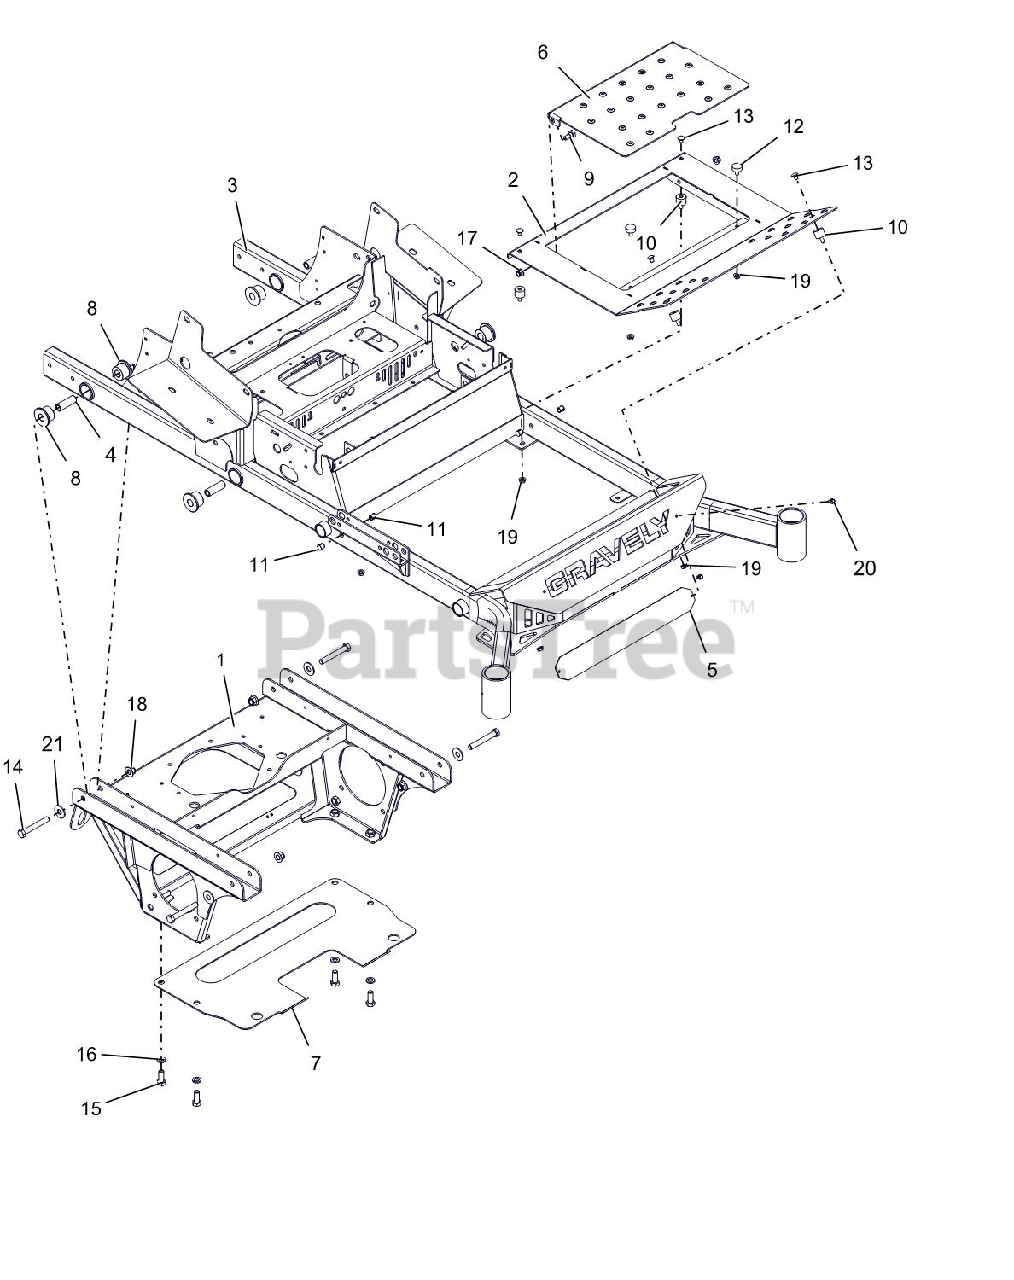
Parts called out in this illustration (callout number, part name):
1	PT200/400 AXLE/ENG FRM WMT-RED
2	FOOTPLATE WLDMT W/SAFETY DECAL
3	52-60"PT200/400 FRAME W/DECALS
4	BSHG-SLV .50X.75X2.23
5	BUMPER LOGO BACKING PLATE -BLK
6	INSPECTION PANEL W/SAFTY DECAL
7	PLATE-TRANSMISSION SKID
8	BSHG-FLG .75X1.51X1.13X2.0 URE
9	BLT,SHLDR EP .38-16X.30 HEX YZ
10	BUMPER,STUD MNTD W/FEMALE INSR
11	PLUG, HOLE .50
12	BUMPER, RUBBER
13	@BLT-RDHDSQNK .31-18X.50 G5YZ
14	@BLT-HEX .50-13X3.50 GR5 YWZC
15	@BLT-HEX .50-13X1.25 GR5 YWZC
16	@WSHR-LK .50X.125 REG YWZC
17	@NUT-LK-NYL-FLG .38-16 YWZC
18	@NUT-LK-NYL-FLG .50-13 YWZC
19	@NUT-SPNLK-FLG .312-18 YWZC
20	SCR-TAP .25-20X.50 HWH TR YWZ
21	@WSHR-FL-STL.563X1.38X.109YWZC
